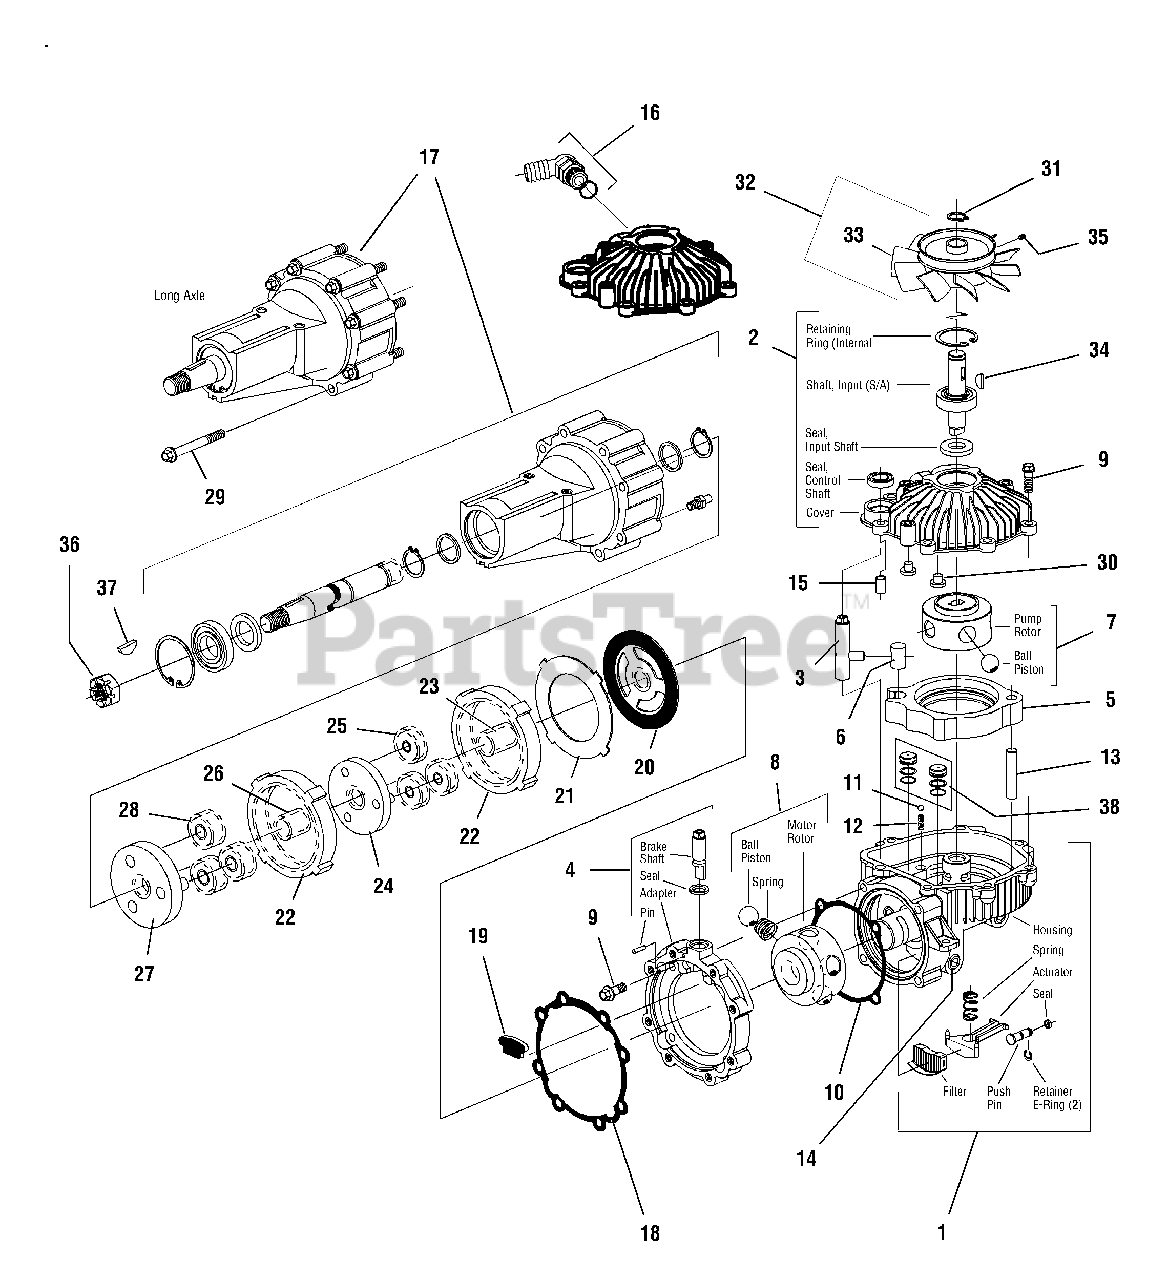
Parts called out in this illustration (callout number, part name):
1	HOUSING ASSEMBLY,
2	COVER ASSEMBLY, Input
3	SHAFT, Control
4	ADAPTER/BRAKE ASSEMBLY
7	ROTOR/BALL, Pump
8	ROTOR/BALL/SPRING, Motor
9	SCREW, Self Tap
11	BALL (Grade 200)
14	PLUG, Socket Pipe
15	BUSHING, Dowel
16	BARB FITTING (Includes O-Ring)
17	AXLE HOUSING ASSEMBLY, Tapered
18	GASKET, Axle Housing
19	PAD, Friction
20	PLATE, Reaction
21	PLATE, Backup
22	GEAR, Ring 54T
23	GEAR, First, 18 Teeth
24	18T PRIMARY CARRIER
25	GEAR, First, 18 Teeth
26	18T SUN GEAR, Second
27	SECONDARY CARRIER
28	GEAR, Second, 18 Teeth
29	SCREW, Hex Flange, 1/4-20
31	RING, Retaining (External)
32	FAN & PULLEY ASSEMBLY (Includes Fan, Ref 33 below).
34	KEY, Woodruff (Input Shaft)
35	SCREW, Hex Socket Set, 1/4-20
36	NUT, Slotted Hex (Tapered Shaft)
37	KEY, Woodruff (Tapered Shaft)
38	PISTON
